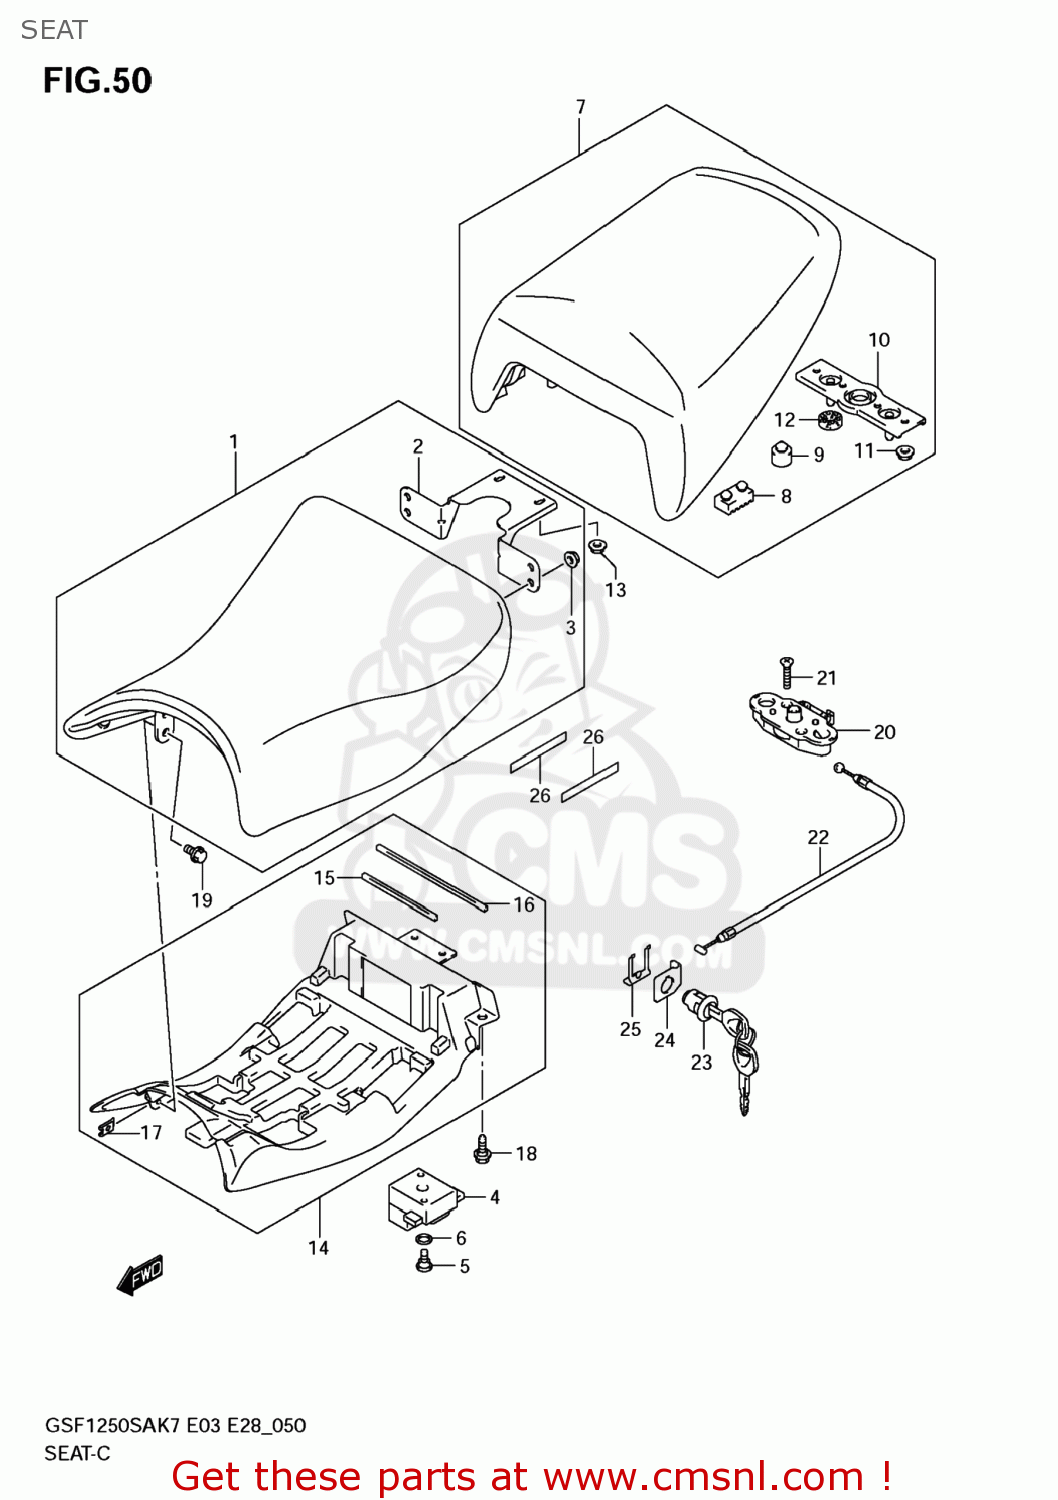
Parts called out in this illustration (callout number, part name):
1	SEAT ASSY
2	BRACKET
3	NUT
4	CUSHION,SEAT
5	SCREW(6X16)
6	WASHER(10.5X18X1)
7	SEAT ASSY,PILL
8	CUSHION
9	CUSHION
10	STRIKER,SEAT L
11	NUT
12	CUSHION
13	NUT
14	COVER,SEAT LWR
15	CUSHION,SEAT LWR COVER FR
16	CUSHION,SEAT LWR COVER RR
17	NUT
18	BOLT(6X16)
19	BOLT
20	BRACKET,SEAT SUPPORT,RIGHT
21	SCREW
22	CABLE,SEAT LOCK
23	LOCK SET,SEAT
24	GUIDE,SEAT LOCK CABLE
25	PLATE,SEAT LOCK ASSY
26	TAPE,SEAT LWR COVER
